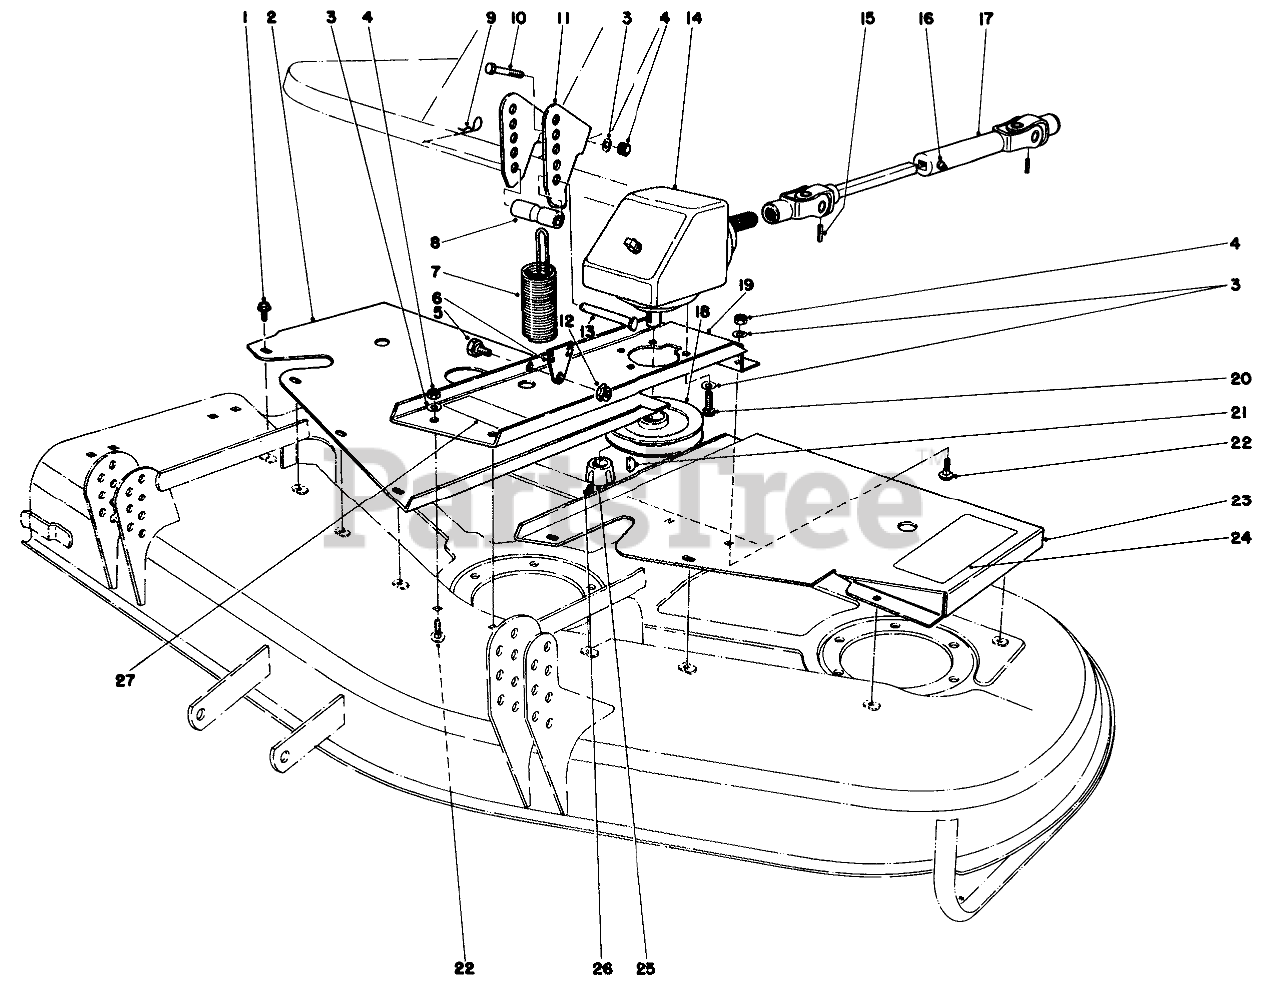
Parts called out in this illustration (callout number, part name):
1	SCREW-HHFTF
2	RH COVER WA R
3	WASHER-LOCK
4	NUT-HEX
5	BOLT-SHOULDER
6	SPRING END R
7	Spring-Extension
8	SPACER
9	PIN-HAIR
10	SCREW-HH
11	SPRING BRACKET R
12	NUT-HHF, WHIZ
13	PIN-CLEVIS
14	GEAR BOX ASM
15	PIN-ROLL
16	FITTING-GREASE
17	UNIVERSAL JOINT
18	PULLEY WA BO
19	Base-Bear Box
20	SCREW-HSH
21	KEY-WOODRUFF
22	SCREW-CARR
23	LH COVER WA R
24	DECAL
25	BUSHING-LOCK, TAPER
26	SCREW-SET, HSH
27	Decal-Caution
